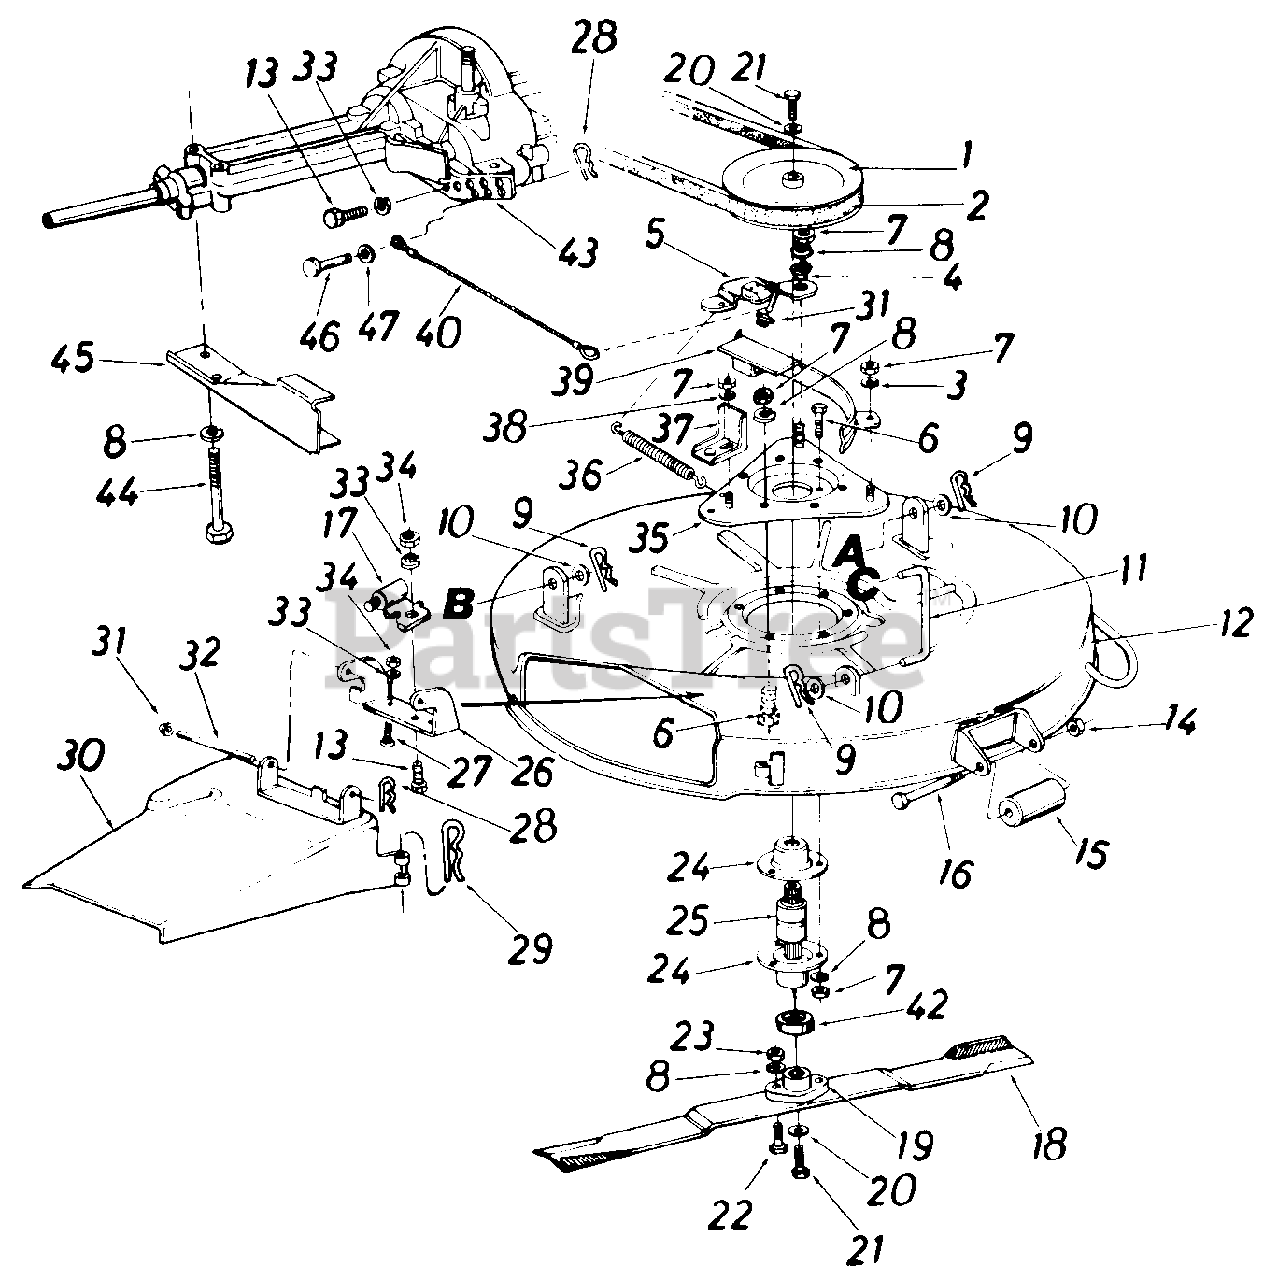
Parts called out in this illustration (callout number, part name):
1	Deck Pulley 7.00" O.D.
2	"V"-Belt 1/2" x 52" Lg.
3	Belleville Washer
4	Shoulder Spacer
5	Blade Brake Brk't. Ass'y.
6	Hex Bolt 5/16-18 x .75" Lg.
7	Hex Nut 5/16-18 Thd.
8	L-Wash. 5/16" I.D.
9	Intem. Cotter Pin 1/2" Dia.
10	Fl-Wash. .531" I.D. x .930"
11	Deck Link 3.9" Lg.
12	30" Deck Ass'y.
13	Hex Bolt 1/4-20 x .62" Lg.
14	Hex Nut 3/8-16 Thd.
15	Skid Roller
16	Shoulder Bolt .498" Dia. x 4.75
17	Safety Switch
18	30" Blade
19	Blade Adapter
20	L-Wash. 3/8 I.D. H.D.
21	Hex Bolt 3/8-24 x .75" Lg.
22	Hex Bolt 5/16-24 x 1.00"
23	Hex Nut 5/16-24 Thd.
24	Housing Bearing Spindle
25	Blade Spindle
26	Deck Hinge Brk't.
27	Carriage Bolt 1/4-20 x .62"
28	Intern. Cotter Pin 5/16" Dia.
29	Cotter Pin
30	Chute Deflector Ass'y.
31	Cap Speed Nut 1/4" Rod
32	Hinge Pin
33	L-Wash. 1/4" I.D.
34	Hex Nut 1/4-20 Thd.
35	Spindle Mtg. Bracket Ass'y.
36	Extension Spring .38" O.D. x 3.25" Lg.
37	Belt Keeper Ass'y.
38	Belleville Wash. 5/16" I.D.
39	Belt Guard
40	Brake Cable Ass'y.
42	Bearing Guard
43	Lower Inside Belt Guard
44	Hex Bolt 5/16-18 x 2.75"
45	Lower Outside Belt Guard
46	Clevis Pin 1/4" x 1/2"
47	Fl-Wash. 1/4" I.D. x .50" O.D.
